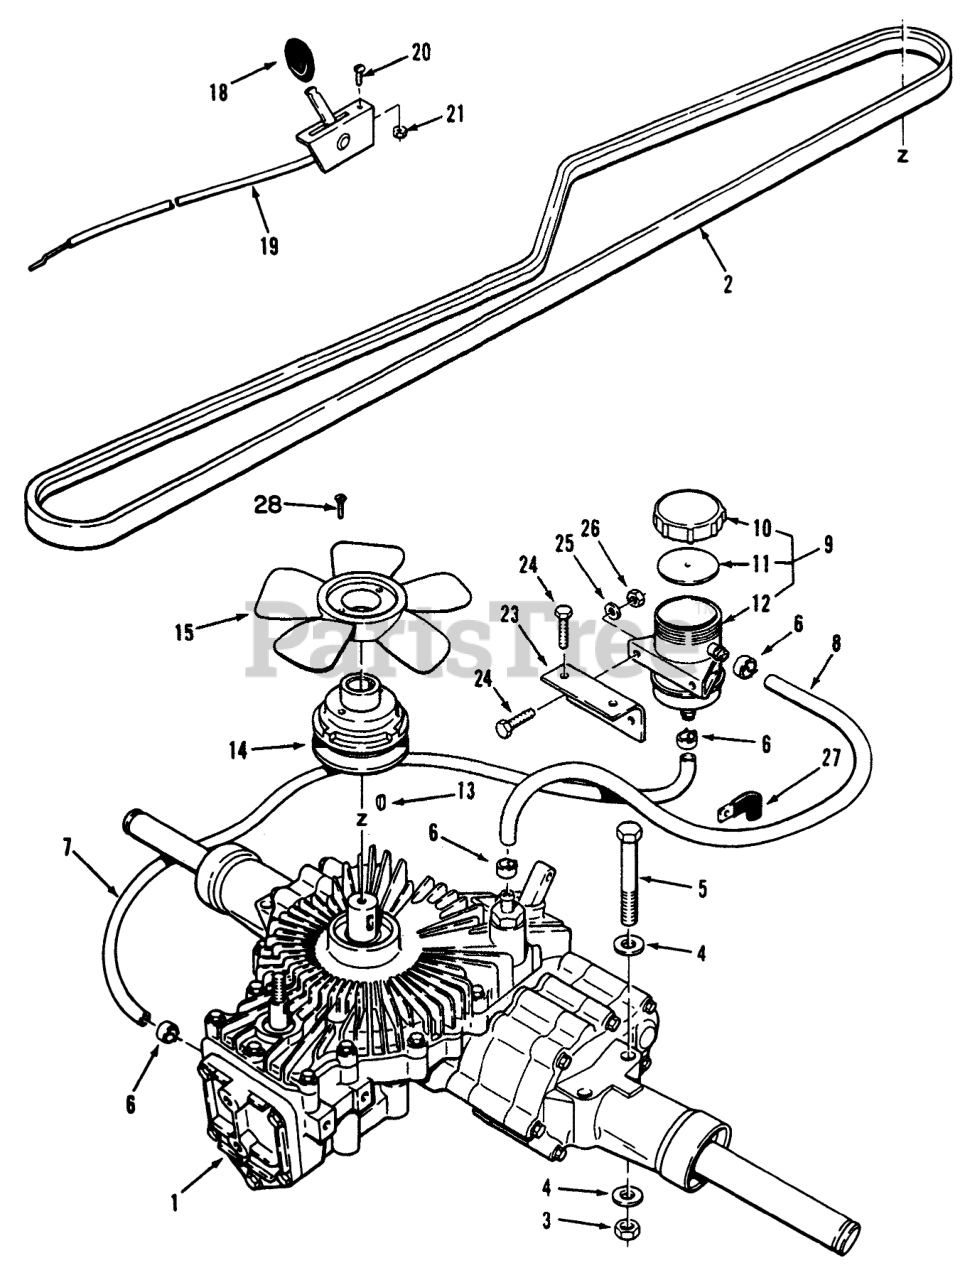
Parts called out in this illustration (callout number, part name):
1	TRANSMISSION 750-019
2	BELT V
3	NUT-LOCK, NI
4	WASHER-PLAIN
5	SCREW-HH
6	CLAMP
7	S/A 9" OF 114702
8	S/A 27" OF 114702
9	Reservoir Assembly (Incl. Ref. #10-12)
10	COVER
11	COVER GASKET
12	RESERVOIR
13	HARD HI PRO KEY
14	PULLEY-HYDRO
15	BLADE-FAN
18	KNOB-THROTTLE
19	CABLE-PUSH VALVE
20	Screw
21	Nut
23	BRKT-RESERVOIR MT R
24	SCREW-HH
25	WASHER-FLAT
26	NUT-LOCK, NI
27	CLIP
28	Screw-Flat Hd.
